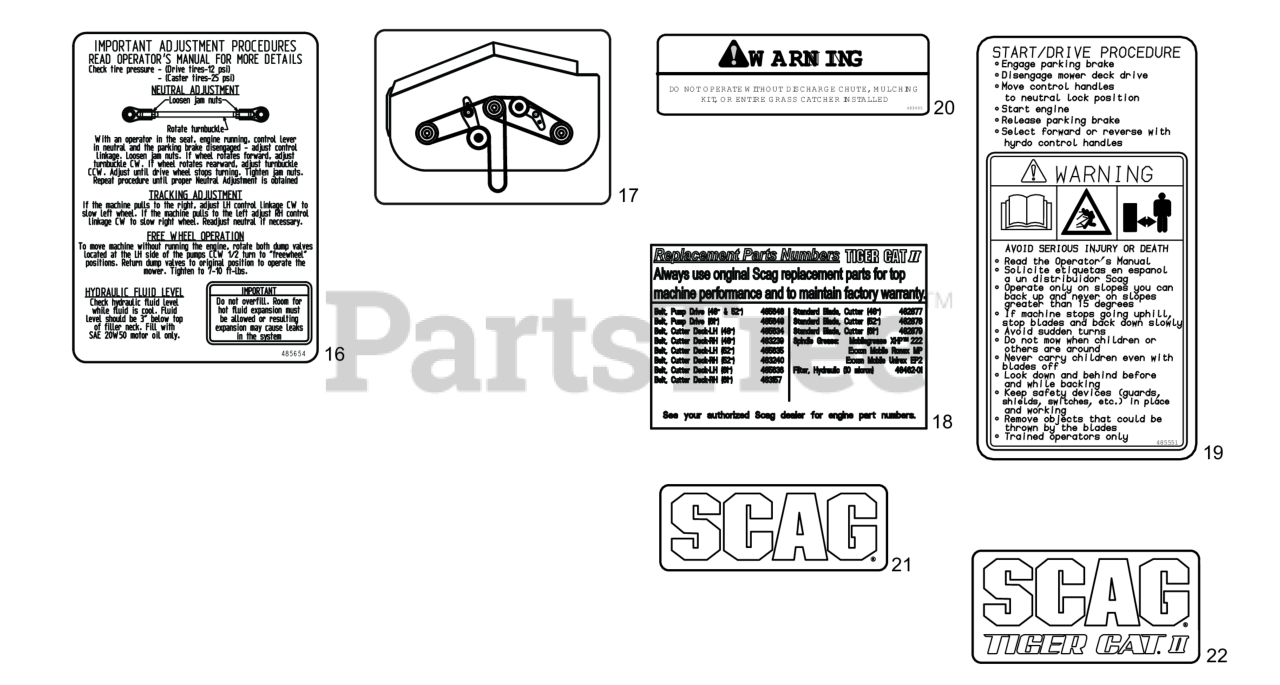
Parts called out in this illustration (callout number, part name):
16	Decal, Seat Support
17	Decal, Cutter Deck Belt Routing
18	Decal, STCII Replacement Parts
19	Decal, Start/Drive
20	Decal, Warning-Discharge
21	Decal, Scag
22	Decal, Scag Tiger Cat II
